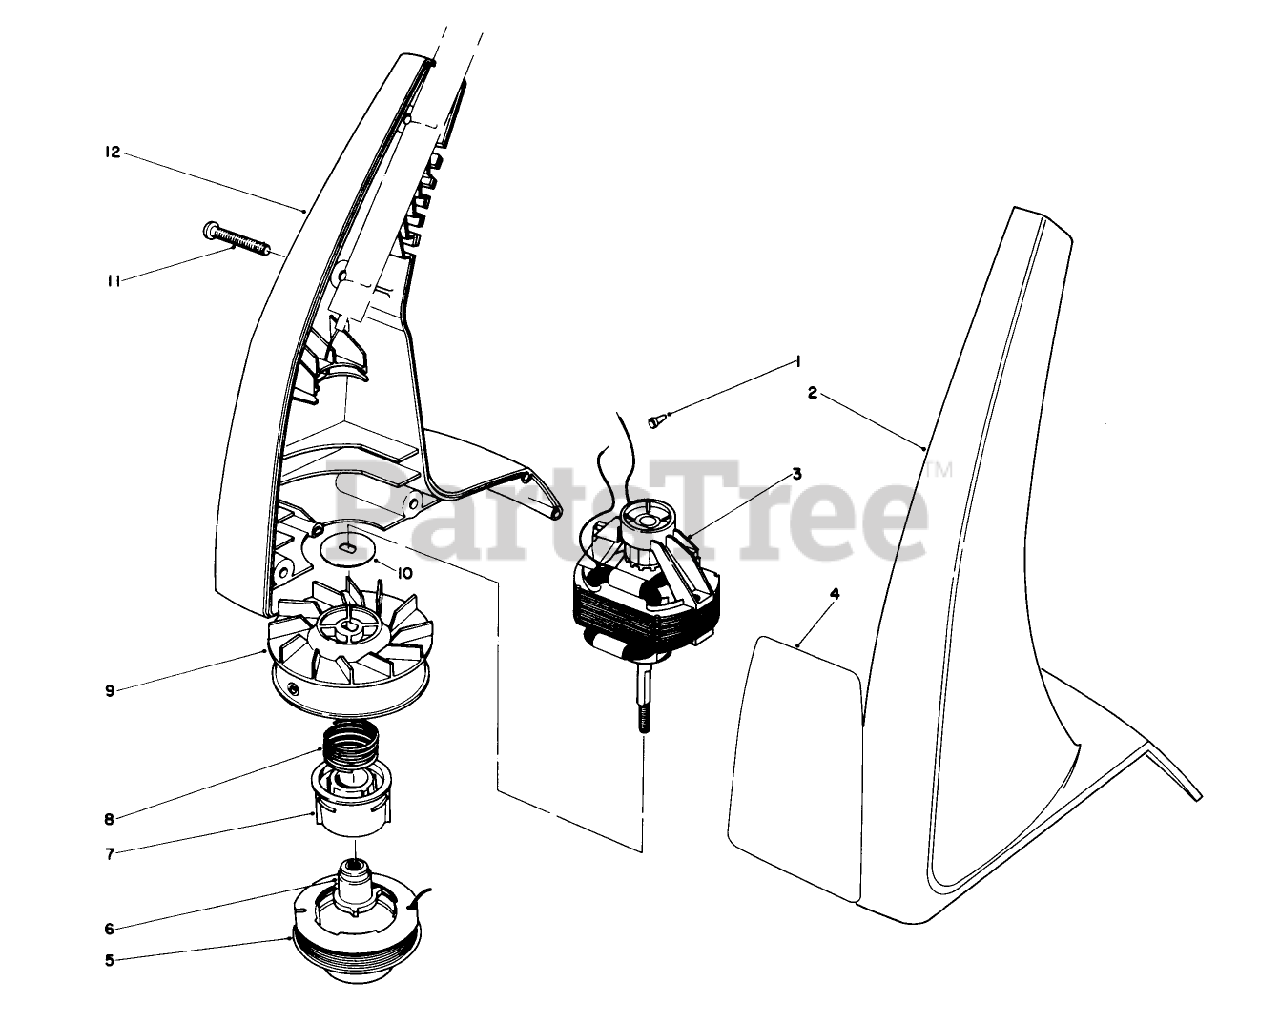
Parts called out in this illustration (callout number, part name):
5	Prewound Spool
6	DRIVER
7	CORE - SPOOL
8	SPRING-COMPRESSION
